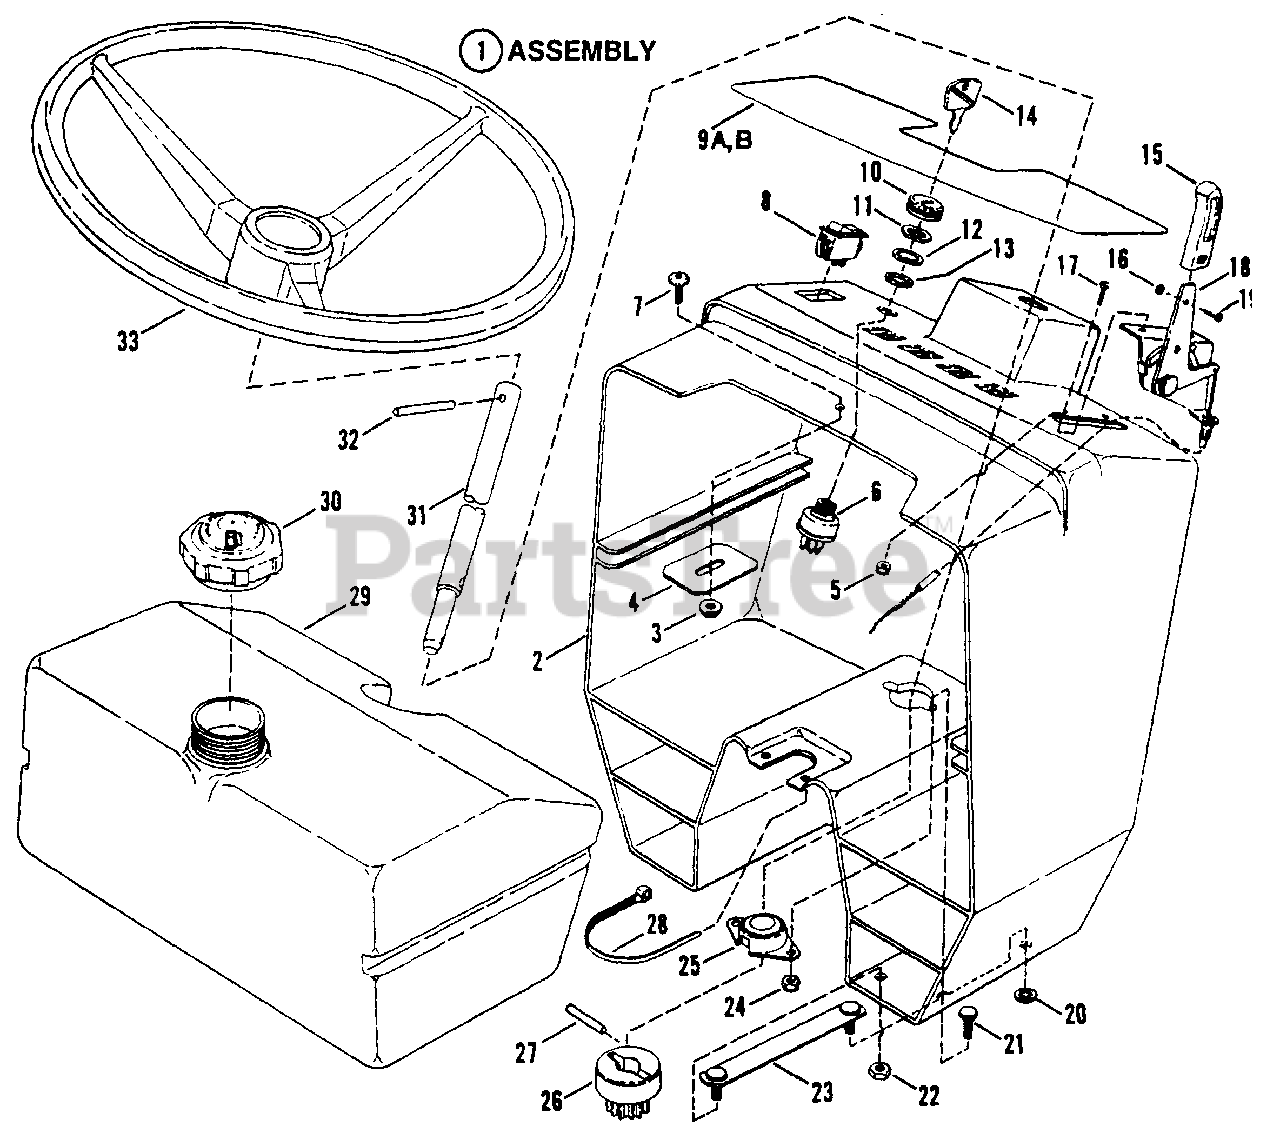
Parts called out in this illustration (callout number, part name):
1	ASSEMBLY, Console
2	CONSOLE
3	NUT, 5/16-18 Hex Flange Lock
4	BRACKET, Hood Latch Catch
5	NUT, #10-24 Hex Nyloc
6	KEYSWITCH
7	SCREW, 5/16-18 x 5/8" Torx, Truss Head
8	SWITCH, Lights
9A	DECAL, Console
9B	DECAL, Console
10	BEZEL
11	NUT, 5/8-32 Hex
12	WASHER, 5/8 Internal Tooth Lock
13	SPACER
14	KEY, Switch (With Cover)
15	HANDLE, Throttle Control
16	NUT, #8-32 Hex
17	SCREW, #10-24 x 5/8" Machine
18	CONTROL, Throttle
19	SCREW, #8-32 x 3/8" Cross-Recessed, Fillester Head
20	RETAINER
21	SCREW, 1/4-20 x 3/4" Hex Hd. Cap
22	NUT, 5/16-18 Hex Center Lock
23	ASSEMBLY, Strap-Clinch Stud
24	NUT, 1/4-20 Hex Nyloc
25	ASSEMBLY, Flange Bearing
26	GEAR, Pinion, Steering Shaft
27	PIN, Dowel, 1/4 x 1 1/4"
28	TIE, Wire
29	ASSM'Y., Fuel Tank
30	CAP, Fuel Tank
31	SHAFT, Steering
32	ROLL-PIN
33	STEERING WHEEL
